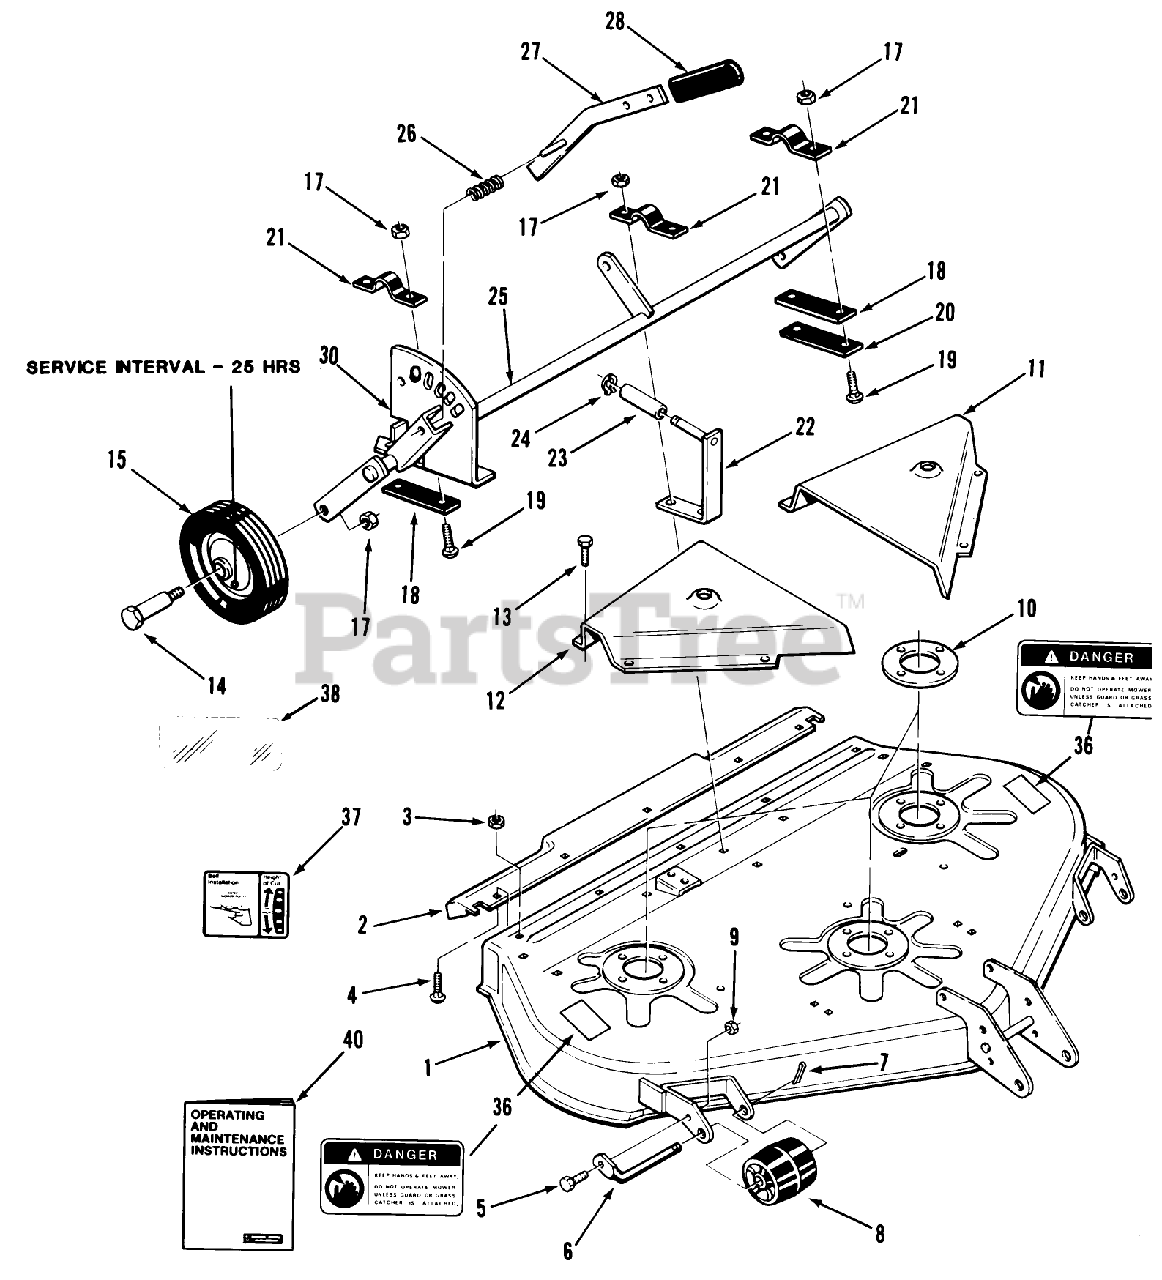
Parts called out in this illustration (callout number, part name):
6	ROLLER-SHAFT
10	PLATE-SPINDLE
13	Bolt
14	BOLT-SHOULDER
15	WHEEL
18	STRAP 1/16 *B
21	CLAMP
26	SPRING-COMPRESSION
37	DECAL-HEIGHT BELT
38	DECAL-OVERLAY
40	Owner-s Maintenance Instructions
